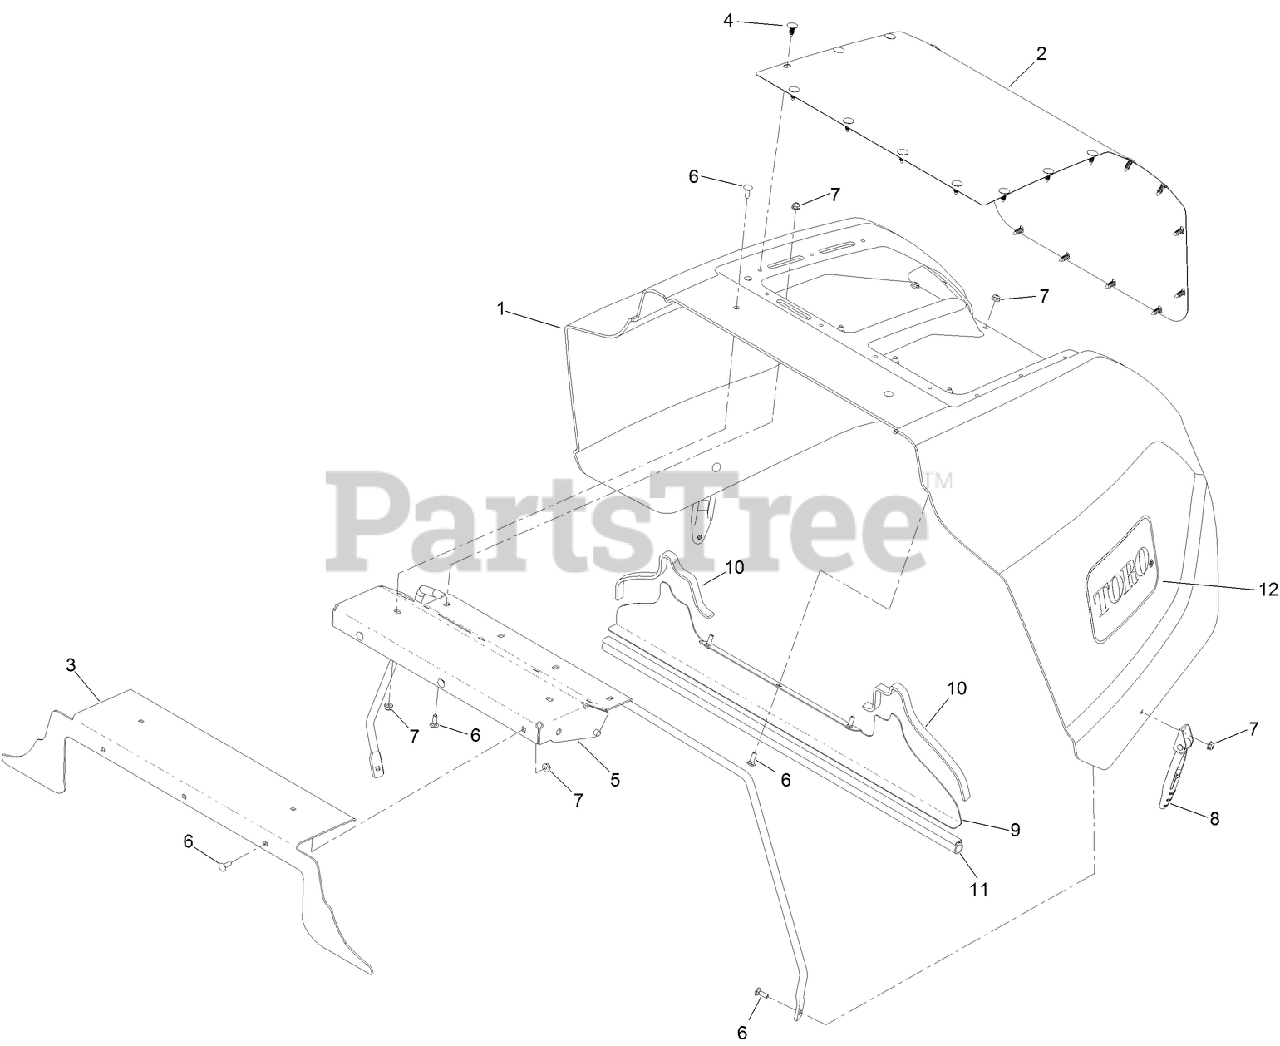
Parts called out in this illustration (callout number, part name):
1	HOOD
2	SCREEN-INTAKE
3	HOOD-BLOCK OFF
4	PLUG-PLASTIC
5	SUPPORT-HOOD
6	BOLT-CARR
7	NUT-HF
8	LATCH-RUBBER
9	PLATE-SEAL
10	SEAL-FOAM
11	SEAL-BULB
12	DECAL
